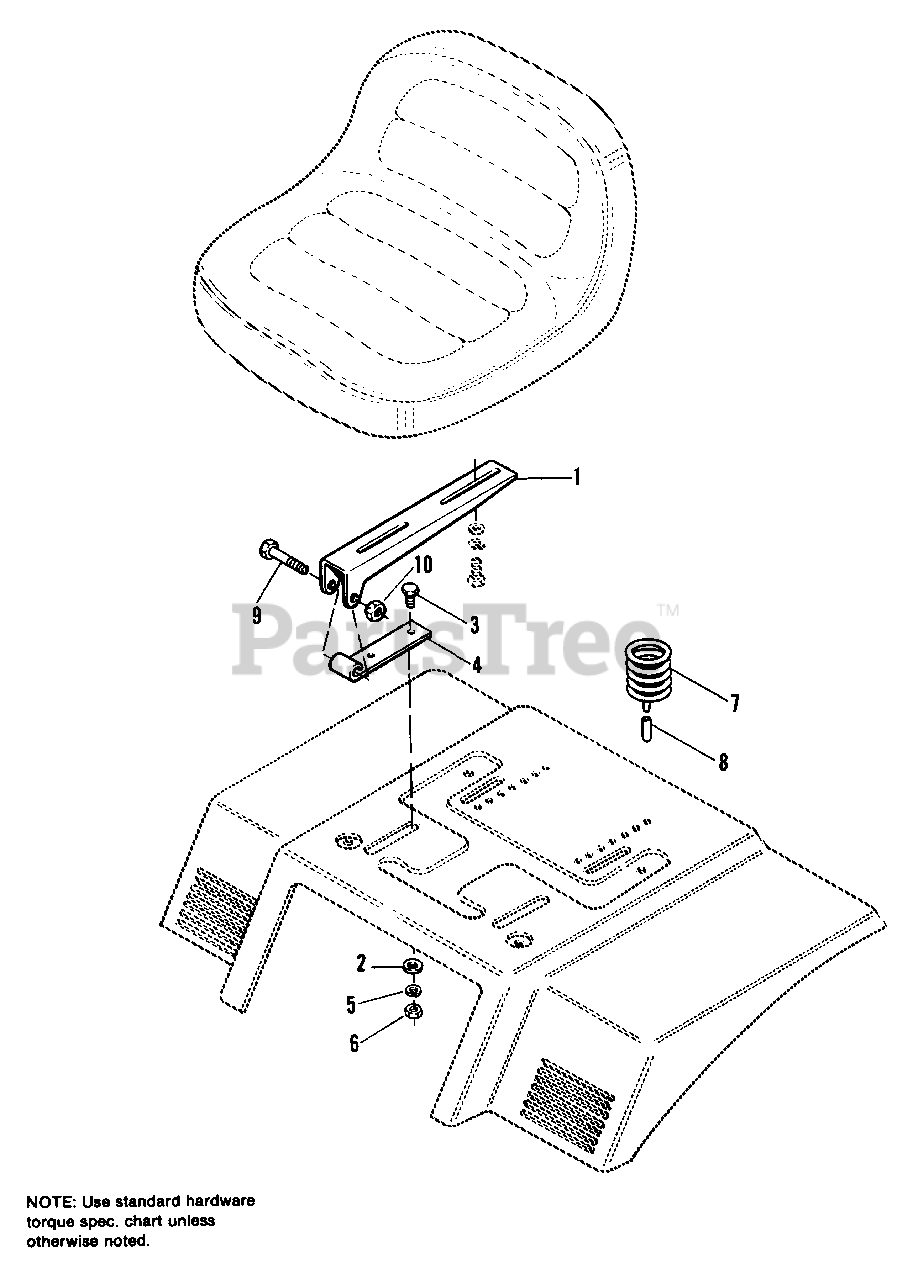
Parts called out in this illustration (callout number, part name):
1	HINGE, Upper
2	WASHER, Plain, 5/16
3	CAPSCREW, Hex. Hd., 5/16-18 x 3/4
4	HINGE, Lower
5	LOCKWASHER, 5/16
6	NUT, Hex, Full, 5/16-18
7	SPRING, Seat
8	COVER, Wire
9	CAPSCREW, Hex Hd., 3/8-16 x 2
10	LOCKNUT, Hex, 3/8-16
